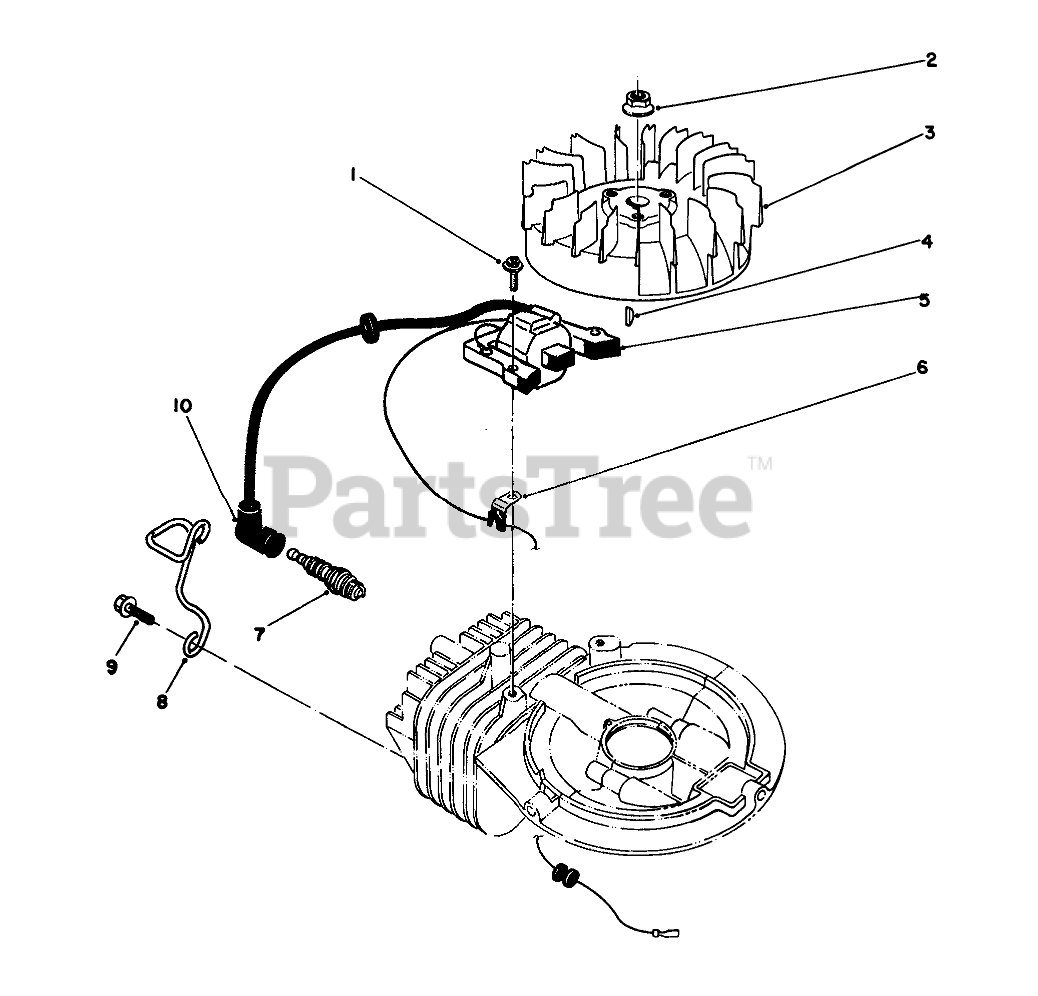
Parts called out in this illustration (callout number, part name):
1	SCREW
3	FLYWHEEL
5	COIL-MAGNETO
6	CLAMP
7	Sparkplug
8	PROTECTOR-PLUG
9	SCREW
10	CAP-SPARKPLUG
